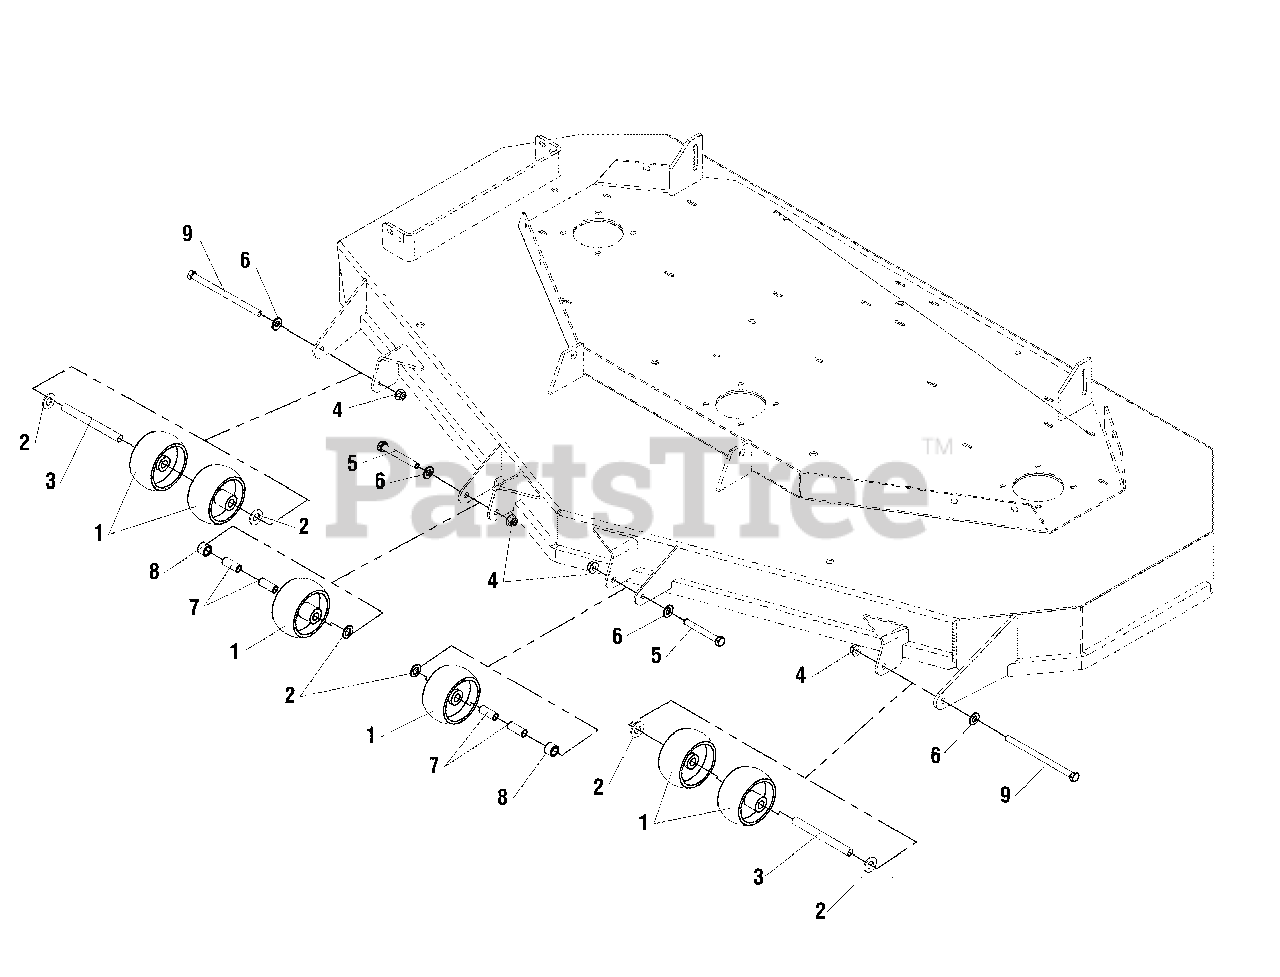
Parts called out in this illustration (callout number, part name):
1	GAUGE WHEEL
2	WASHER, 1/2" GD9 YZ
3	SPACER, .38 X .50 X 5.06
4	NUT, 3/8-16 HEX NYLOCK FLANGE
5	BOLT, 3/8-16 X 3-1/2" GD5 YZ
6	WASHER 3/8" SAE
7	SPACER, .38 X .50 X 1.25
8	SPACER, .51 X .75 X .56
9	BOLT, 3/8-16 X 6" GR5 YZ
